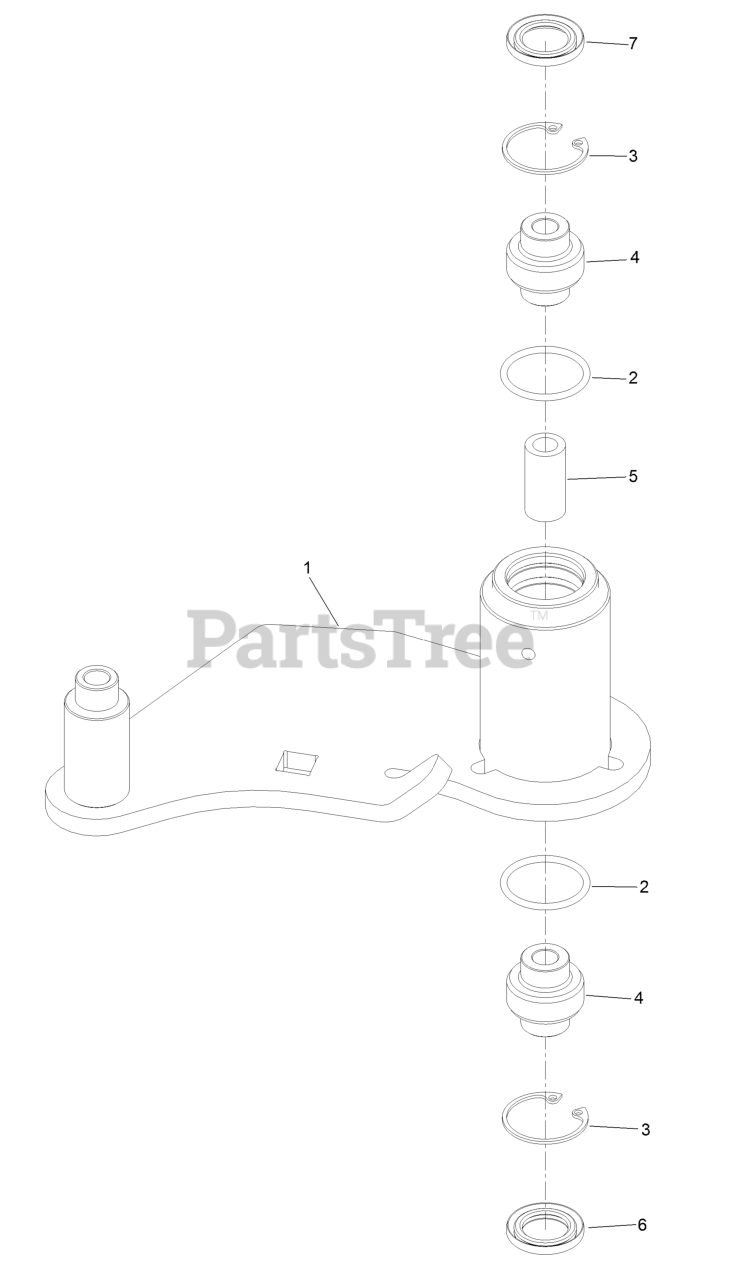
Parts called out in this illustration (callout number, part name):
1	Idler-Deck
3	Ring-Snap
4	Bearing-Spherical
6	Seal-Lip, Double
7	Seal-Lip, Single
